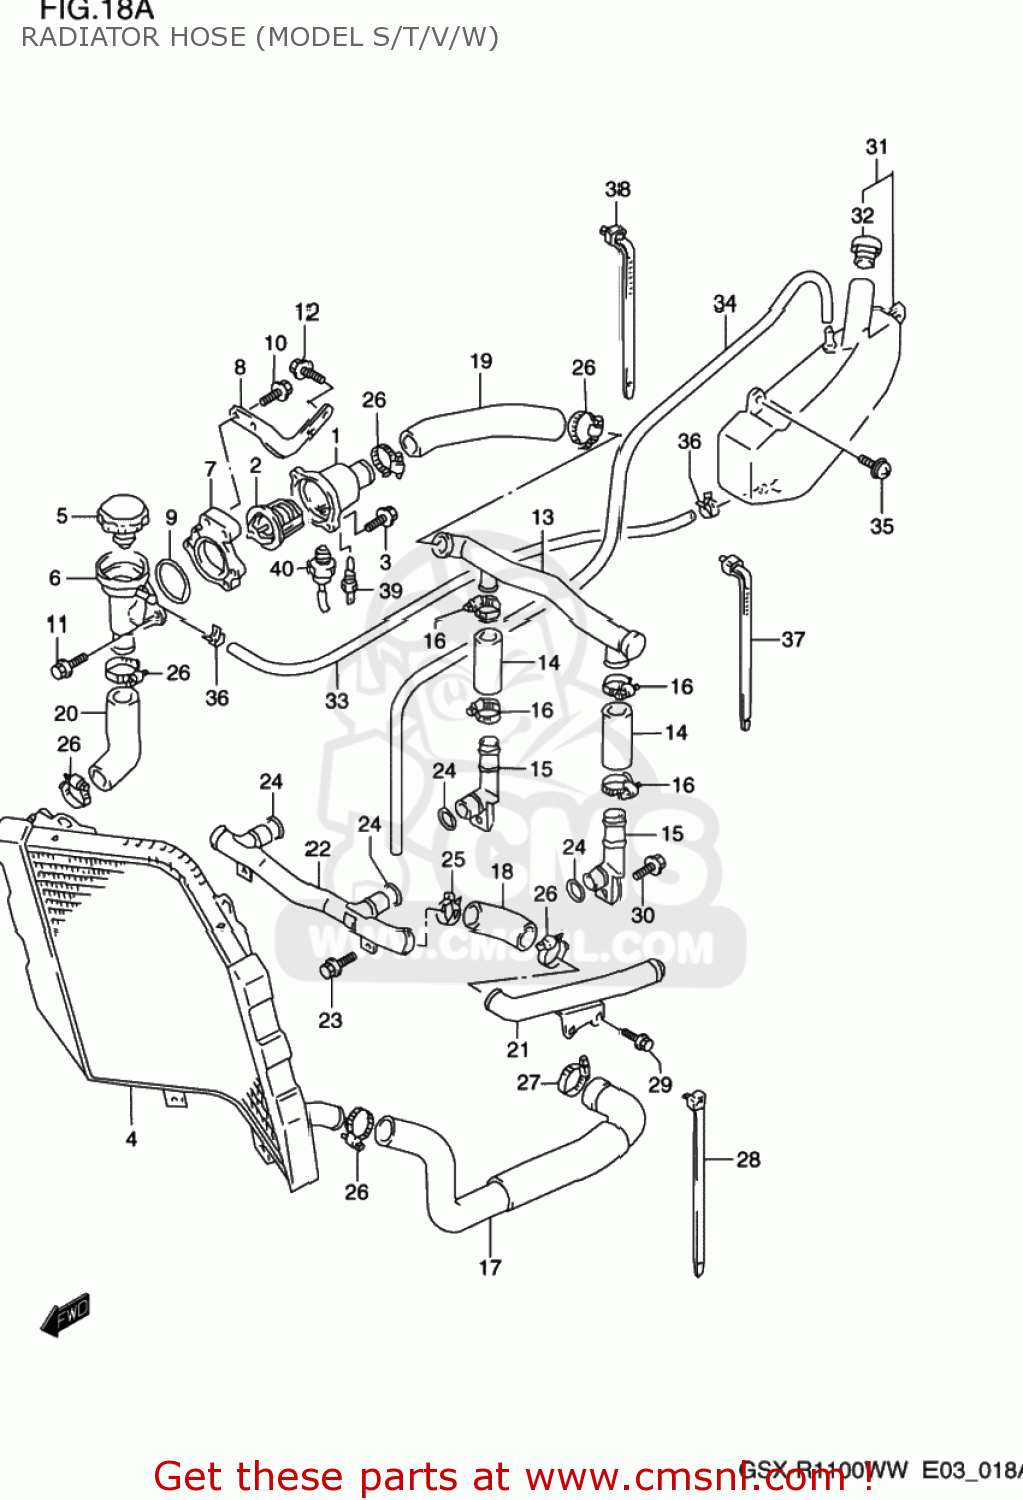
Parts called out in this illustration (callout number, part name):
1	CONNECTOR,THERMOSTAT INLET
2	THERMOSTAT,WATER
3	BOLT
4	RADIATOR ASSY,WATER
5	CAP COMP,RADIATOR 1.1
6	CONDUCTION,RADIATOR
7	BRACKET,CONDUCTION
8	BRACKET,CONDUCTION BRACKET
9	O RING(D:2.4,ID:43.2)
10	BOLT
11	BOLT
12	BOLT
13	PIPE,HEAD OUTLET NO.2
14	HOSE,WATER
15	PIPE,HEAD OUTLET
16	CLAMP
17	HOSE,WATER PUMP INLET
18	HOSE,WATER
19	HOSE,HEAD OUTLET
20	HOSE,RADIATOR INLET
21	PIPE,CYLINDER SIDE
22	PIPE,CYLINDER INLET
23	BOLT
24	O RING(D:3.2,ID:17.8)
25	CLAMP
26	CLAMP
27	CLAMP
28	CLAMP
29	BOLT
30	BOLT
31	TANK ASSY,RESERVOIR
32	CAP,RESERVOIR TANK
33	HOSE,RESERVOIR TANK INLET
34	HOSE,RESERVOIR TANK
35	SCREW(6X20)
36	CLIP
37	CLAMP L:165
38	CLAMP L:165
39	GAUGE ASSY,WATER TEMP
40	SWITCH,RADIATOR FAN
